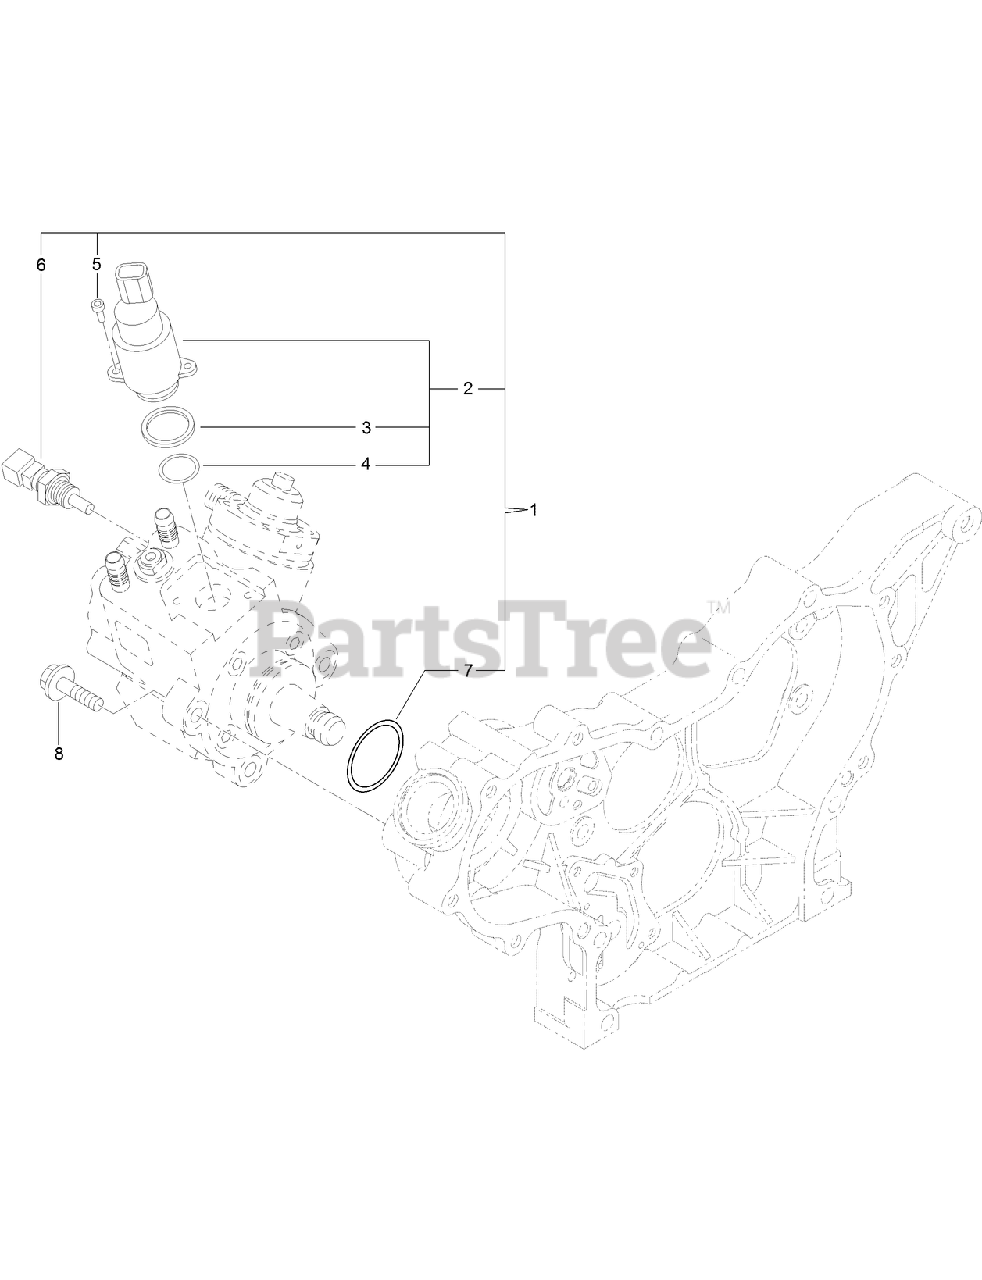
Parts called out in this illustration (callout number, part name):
1	FUEL PUMP ASM
2	VALVE ASM
3	RING-SEALING
4	O-RING
6	SENSOR-TEMPERATURE
7	O RING-PUMP, FUEL
